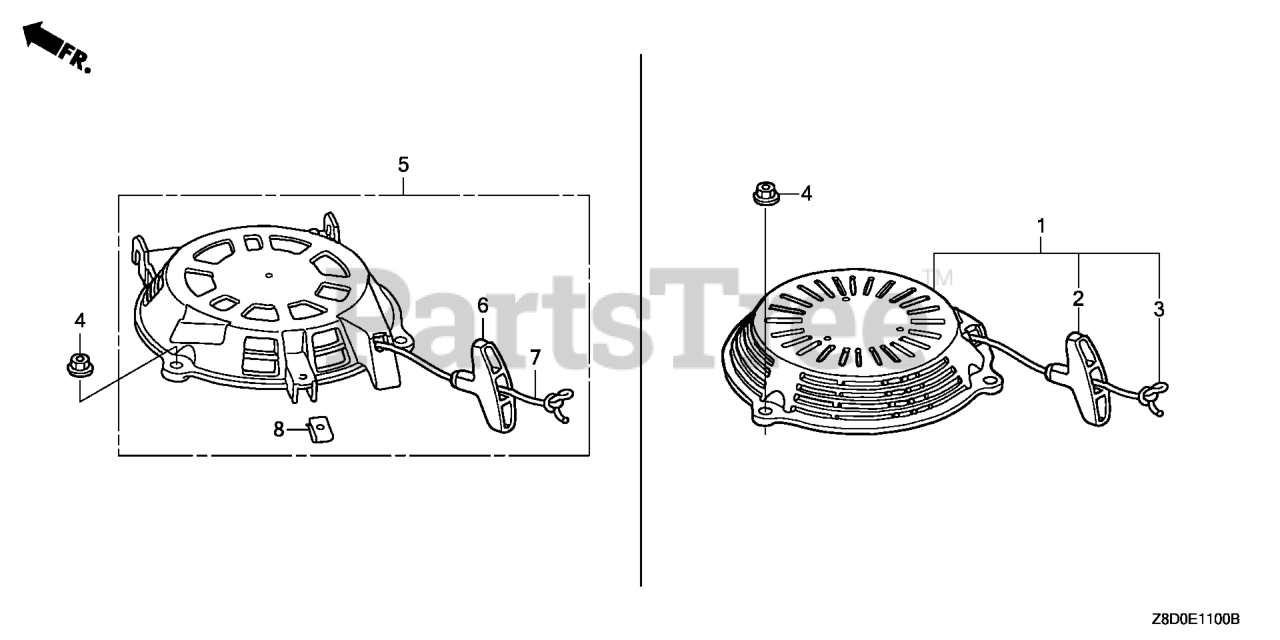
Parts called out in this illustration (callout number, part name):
4	NUT, FLANGE (6MM)
5	STARTER ASSY., RECOIL (LONG ROPE)
6	KNOB, RECOIL STARTER
7	ROPE, RECOIL STARTER (Honda Code 5580642). (#3.5X90")
